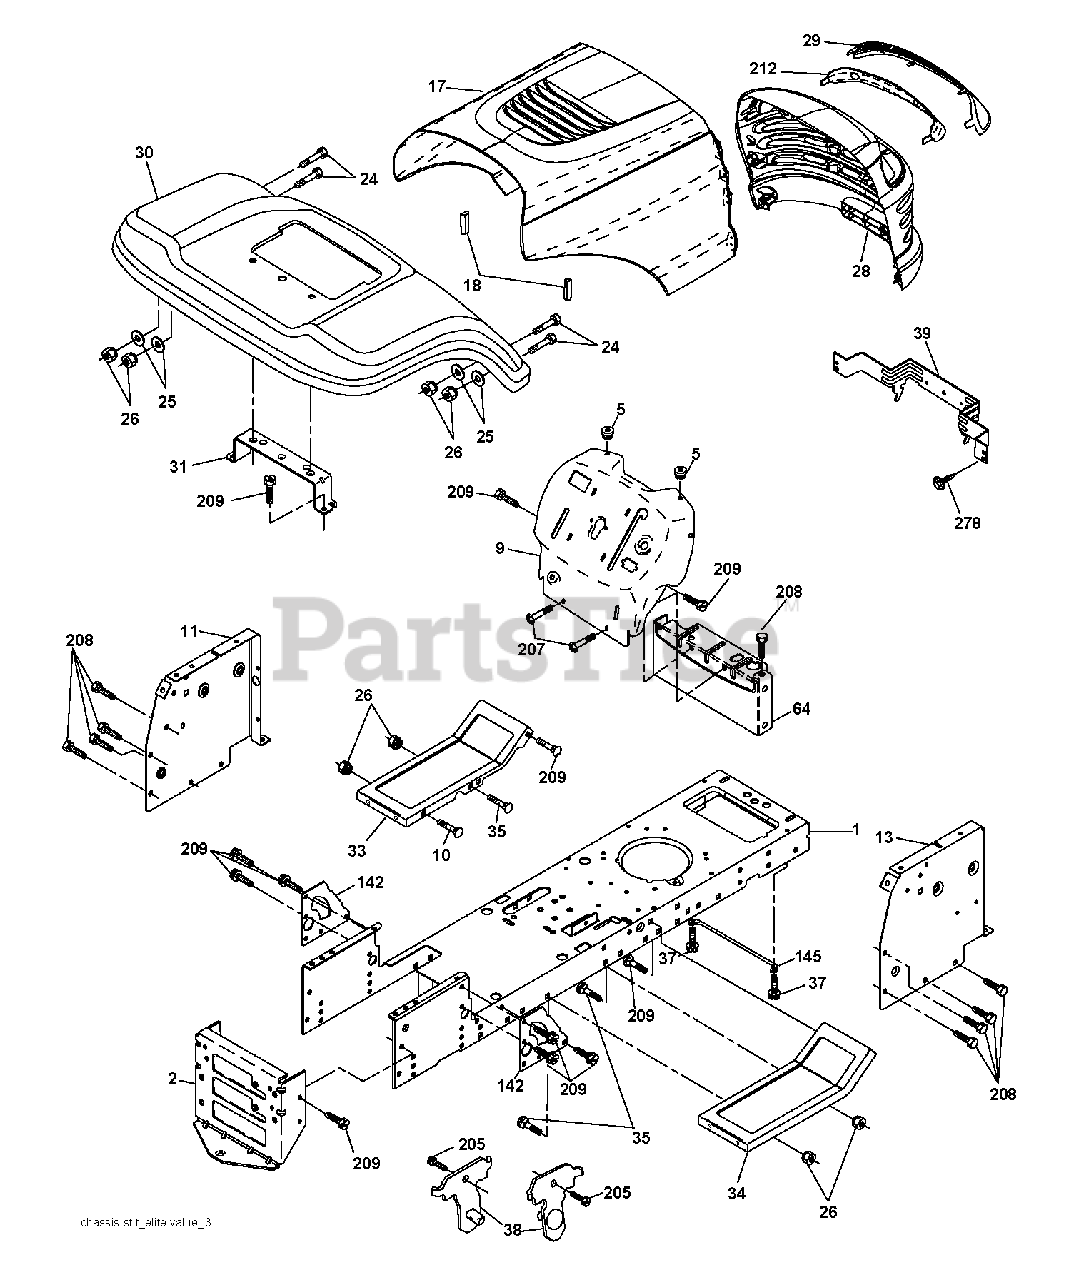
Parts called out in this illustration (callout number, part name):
1	CHASSIS STAMPING
2	DRAWBAR, 12GA
5	BUMPER.RUBBER.HOOD
9	DASH
10	BOLT D
11	PANEL.DASH.LH.LTX
18	BUMPER.HOOD.LARGE.1.75"
25	WASHER
26	NUT
31	BRACKET FENDER
38	BRACKET.ASM.PIVOT.MOWER.REAR
39	BRACKET PIVOT
64	DASH LOWER
142	PLATE REINFORCEMENT
145	ROD.PIVOT.HOOD
207	SCREW, 5/16-18 X 1/2
208	SCREW 3/8-16X1/2
209	SCREW, 3/8-16X3/4
278	SCREW.#10 X 0.750.BOS THREAD
